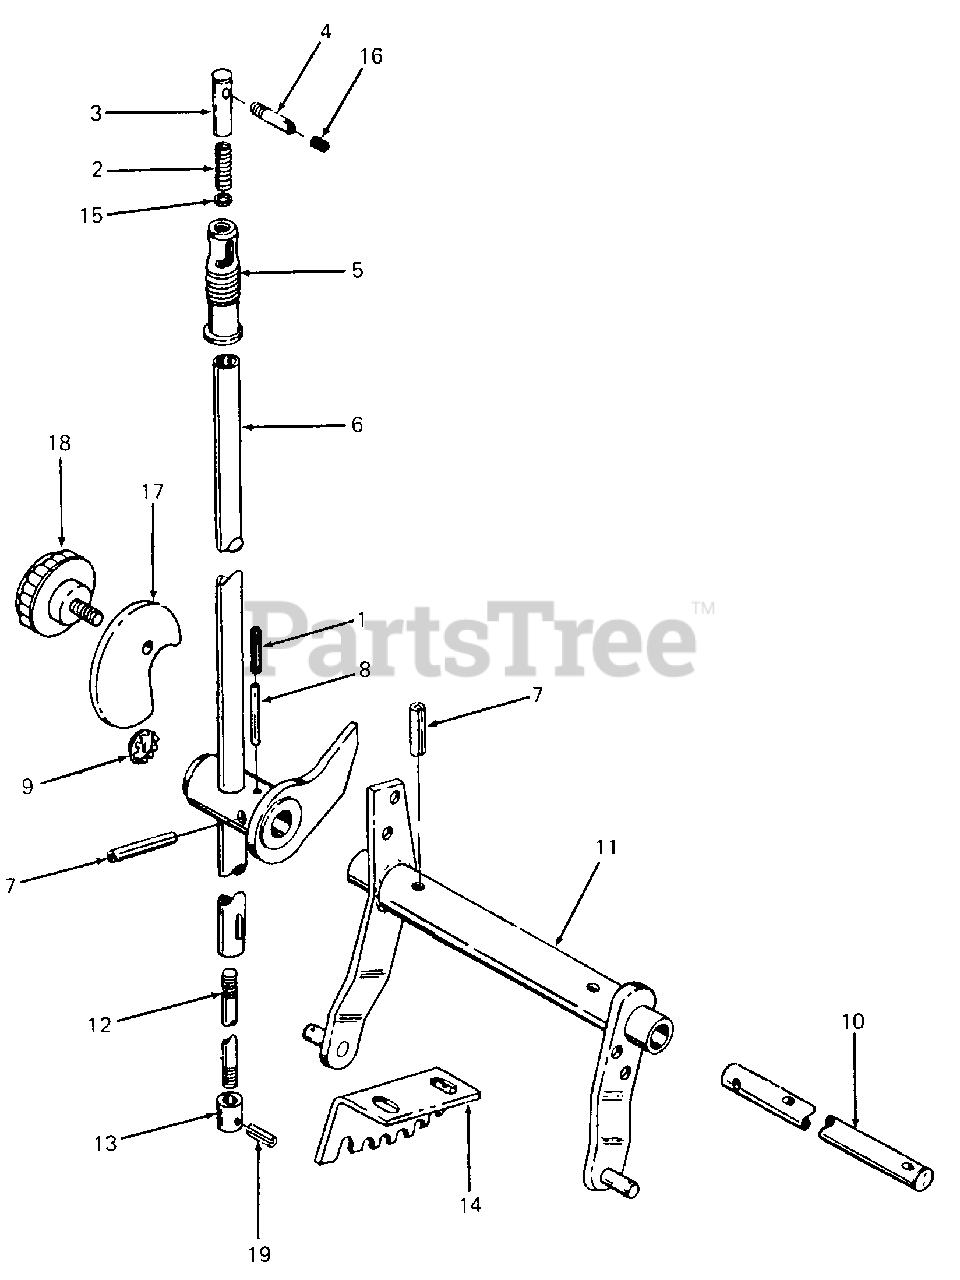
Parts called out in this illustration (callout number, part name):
1	Pointer, Lift
2	Spring, Lift Handle
3	Pin, Lift Handle Float
4	Pin, Float Lock
5	Grip, Lift Handle
6	Handle, Lift
7	Pin, Roll, 3/8 Dia X 2.0 Lg
8	Pin, Roll, 3/16 Dia X 3.0 Lg
9	Plug, Button
10	Rockshaft
11	Lift Assembly, Rockshaft
12	Rod, Handle
13	Rod, Handle Release
15	Washer, Flat, .344 X .532 X .06 Thk (HDN)
16	Cap, Float Lock Pin
19	Pin, Spirol Spring, 5/16 X 1.5 Lg
